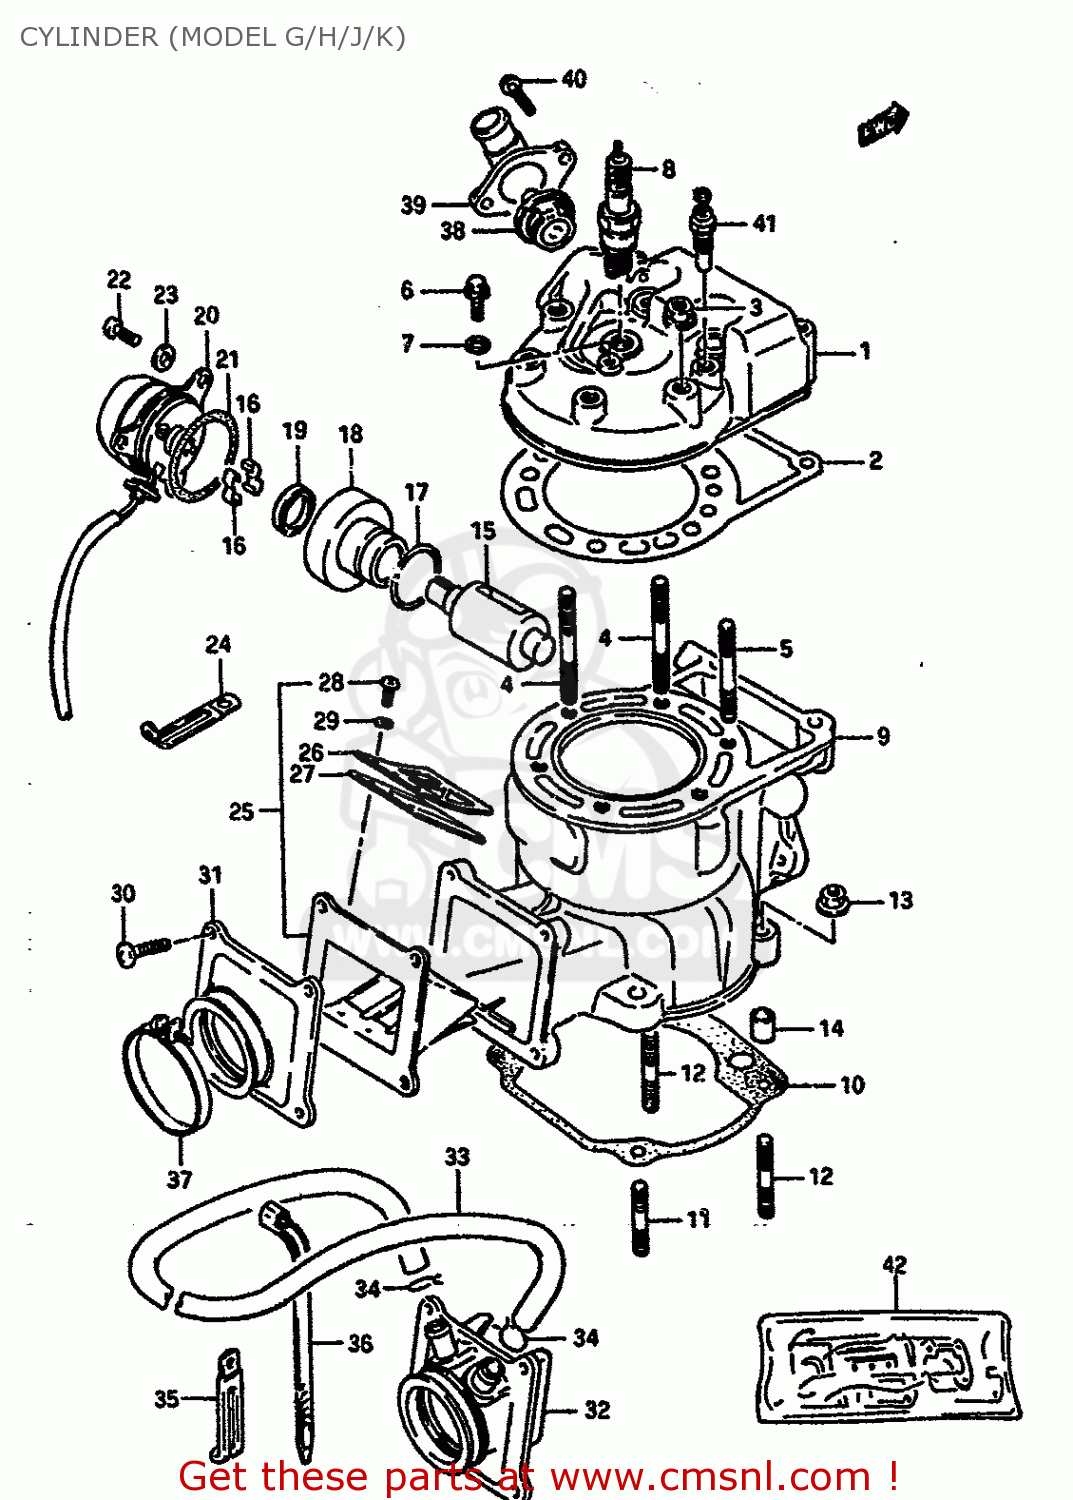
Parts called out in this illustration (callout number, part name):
1	CYLINDER HEAD
2	GASKET,CYLINDER HEAD (NA)
3	NUT 8MM
4	STUD BOLT (8X50)
5	STUD
6	UNION
7	GASKET(6.2X11X1).2 (NAS)
8	PLUG,SPARK
9	CYLINDER
10	GASKET,CYLINDER
11	STUD BOLT (8X25)
12	STUD
13	NUT 8MM
14	PIN
15	VALVE, EXHAUST
16	SPRING,EXHAUST VALVE
17	O RING(D:2.4,ID:28.8)
18	HOLDER,EXHAUST VALVE
19	SEAL,OIL(15X24X5)
20	SOLENOID ASSY
21	GASKET,SOLENOID
22	SCREW
23	WASHER
24	CLAMP
25	VALVE ASSY,REED
26	STOPPER
27	VALVE,REED
28	SCREW
29	LOCK WASHER
30	SCREW
31	PIPE,INTAKE
32	PIPIE,INTAKE
33	HOSE 8X12.5
34	CLIP
35	CLAMP
36	CLAMP(L:125)
37	CLAMP
38	THERMOSTAT,WATER 65 DEG
39	COVER, THERMOSTAT
40	SCREW
41	GAUGE,WATER TEMP
42	GASKET SET (NA)
